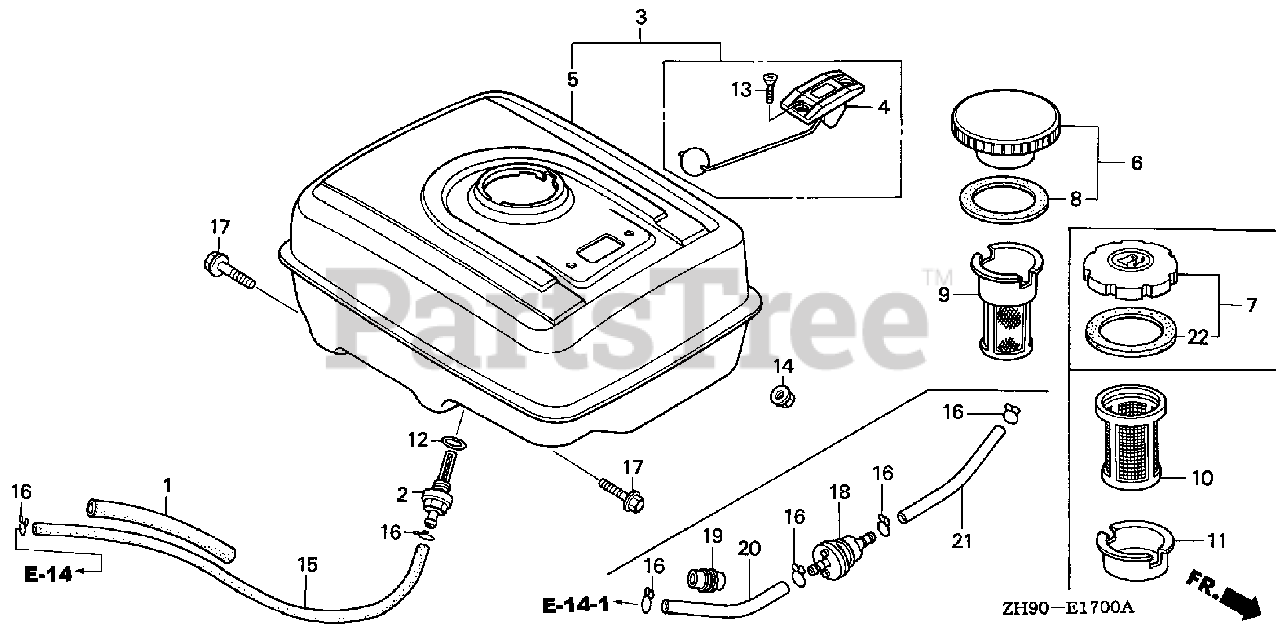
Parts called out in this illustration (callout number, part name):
1	RUBBER, SUPPORTER (107MM)
2	JOINT, FUEL TANK
5	TANK, FUEL *NH1* (BLACK)
7	CAP, FUEL FILLER
12	O-RING (13.5X1.5) (ARAI)
14	NUT, FLANGE (8MM)
15	BULK HOSE, FUEL (4.5X3000) (4.5X222)
16	CLIP, TUBE (B8)
17	BOLT, FLANGE (8X25)
22	GASKET, FUEL FILLER CAP
